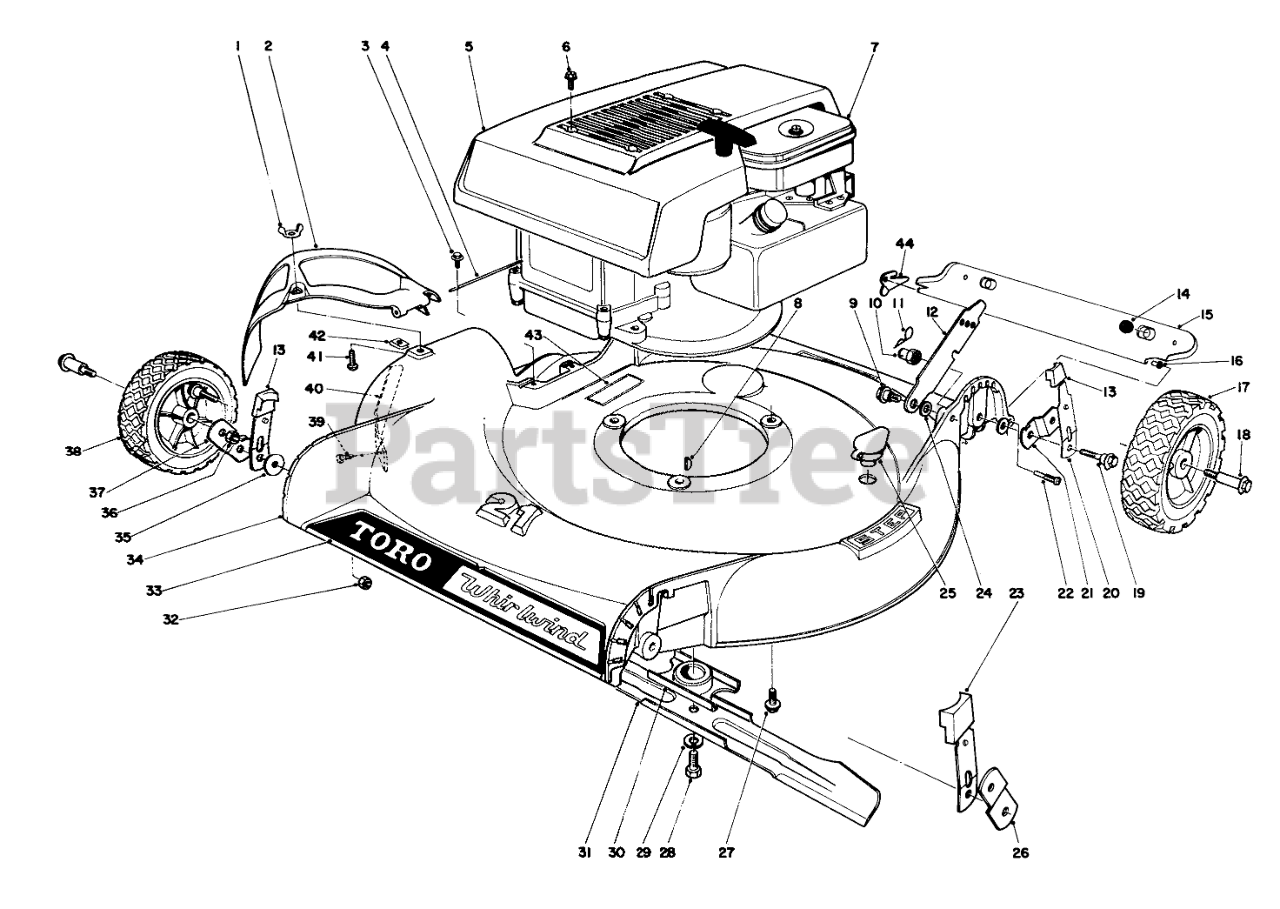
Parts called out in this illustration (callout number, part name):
1	NUT-WING SPECL
2	Deflector
3	SCREW
4	HINGE PIN
5	Shroud
6	8X1/2 SELF TAP SCREW
7	Engine
8	KEY-WOODRUFF
9	SCREW-SHOULDER
10	HANDLE PIVOT NUT
11	PIN-COTTER, HAIR
12	Latch
13	Arm Knob
14	SKID BUTTON
15	Safety Shield (Incl. Ref. 15 & 16)
16	SAFTEY SHIELD BUSHING
17	WHEEL ASM 8
19	PIVOT SCREW
20	Spring Arm
21	PIVOT ARM PLATED
22	SAFTEY SHIELD SCREW
23	Arm Knob
24	SPACER
25	WASHOUT PLUG
26	PIVOT ARM C PLTD
27	SCREW-HWHTF
28	SPECIAL SCREW
29	WASHER-LOCK
30	Blade Retailer
31	Blade
32	Nut
33	Decal
34	Housing
35	WASHER-PIVOT
36	Nut
37	PIVOT ARM D PLTD
38	WHEEL ASM 7
39	SCREW-HWH
40	Bar Safety
42	NUT-SPEED
43	Decal
44	Restraint R.H.
